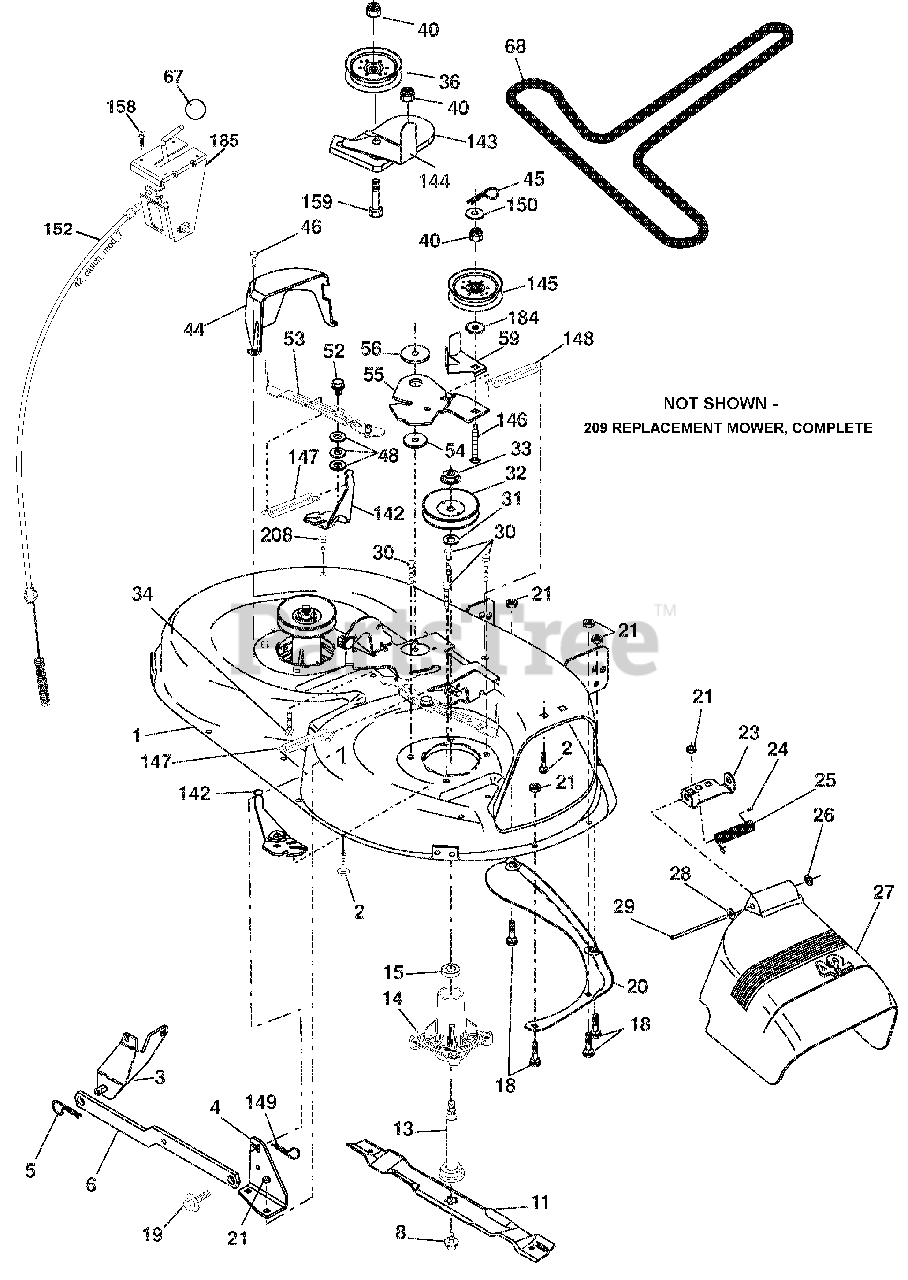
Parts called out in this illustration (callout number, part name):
1	Mower Deck Assembly, 42"
3	Bracket Asm Fr. Sway Bar 3/42
4	Bracket Asm Deck 42" Sway Bar
5	Retainer Spring
6	Bar Sway Deck
8	BOLT/WASHER ASM.7/16-20.UNF
11	BLADE.MOWER.42"HI LIFT PREMIUM
11	BLADE, HUSQ MULCH KIT
11	Blade Mulching 42 Premium (Fo
11	Blade 42SP" 3N1
11	Blade 42SP" 3N1 Premium
13	SHAFT ASM.MNDRL.N/GREASEABLE38
14	HOUSING.MANDREL.4PT.SERVICE
15	BEARING.BALL.MANDREL
18	BOLT.RDHD.SQNK.5/16-18 X 5/8
19	Bolt, Shoulder
20	BAFFLE.VORTEX.42.STD/HEAVY DTY
21	Nut, Hex, Crownlock 5/16-18
23	Bracket, Deflector Mower 42"
24	CAP.SLEEVE..80X.112.BLK.MOWER
25	SPRING.TORSION.DFL.38/42/46.GR
26	NUT.PUSH.PHOS.& OIL
27	Shield, Deflector 42" Blk
28	Washer 11/32 x 5/8 x 16 Ga.
29	ROD.HINGE.42/46"
30	SCREW.THD ROLL.DOD PT.HEX
31	WASHER.SPACER.MANDREL
32	MANDREL.PULLEYS.42,44,50
32	MANDREL ASM.SUB.N-GRS.4 BOLT
33	NUT.FLANGE.LOCK.TOP
34	BOLT.CARR.SH.3/8-16X1-1/2.GR5
36	PULLEY, IDLER, FLAT
40	Nut, Hex, Flangelock 3/8-16
44	Guard, Mandrel, LH
45	Retainer Spring
46	SCREW.THD.ROLL.1/4-20 X 5/8
48	Washer, Hardened
52	Bolt, Shoulder 5/16-18 unc
53	Arm Assembly, Pad, Brake
54	WASHER.FLAT.HARDENED
55	Arm, Idler
56	Spacer, Retainer
59	GUARD.TUV.IDLER
67	Knob Round
68	V-Belt, 42" Mower
142	Anchor Spring Brake Mower
143	Bracket Arm Idler 42"
144	KEEPER BELT 42" CLUTCH CABLE
145	PULLEY IDLER FLAT
146	BOLT.CARRIAGE.IDLER
147	Spring Extension
148	Spring Return Idler
149	Retainer Spring Yellow
150	WASHER.9/32 X 3/4 X 10 GA.
152	Clutch Cable 42"
158	Screw 1/4-20 x 1/2
159	Bolt Rdhd Sqn 3/8-16 unc x 1-3
184	Washer 13/32 x 7/8 x 10 Ga.
185	Head Asm Cable Clutch\
208	SCREW.THDROL.3/8-16X1/2.TYT.BL
209	Replacement Mower, Complete
